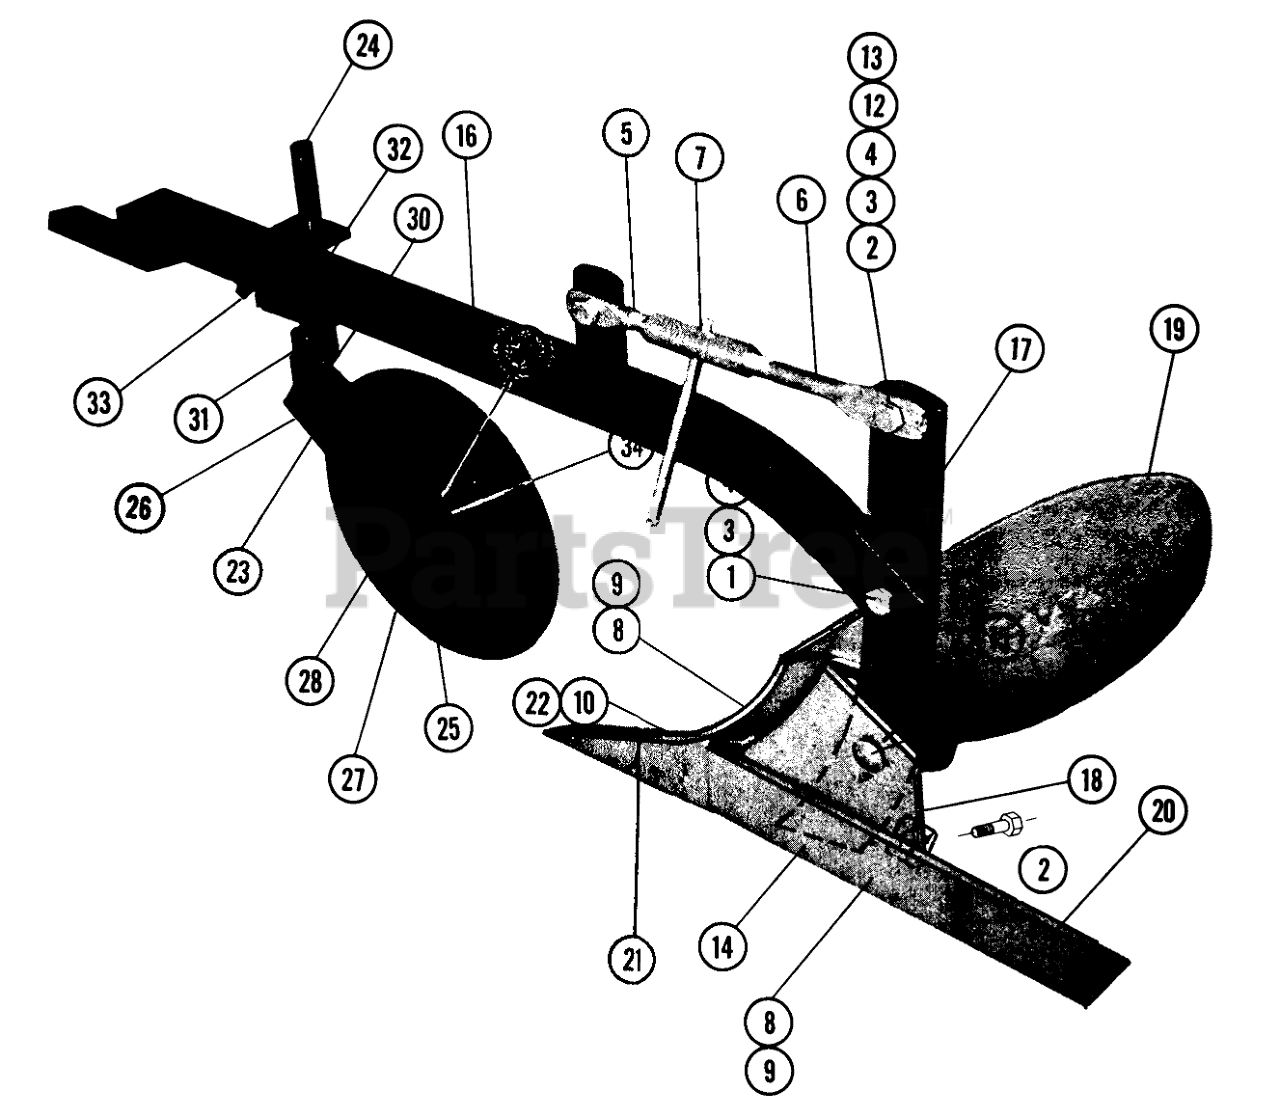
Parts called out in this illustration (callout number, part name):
1	Bolt-Hex 1/2-13 x 2
2	Bolt Hex 1/2-13 x 1 1/2
3	Lockwasher
4	Nut, 1/2-13
7	Coupling-Adjusting
8	Bolt-Plow 3/8-16 x 1
9	Nut-Sq. 3/8-16
10	Nut-Sq. 7/16-14
11	Nut-Square-1/2-13
12	5353 GILSON LGT WEI
13	Washer 9/16 SAE
14	Washer 9/16 SAE
15	Bolt-1/2-13 x 1-1/2 Carr.
16	Ass-y. Beam
17	Standard Assembly
18	Frog
19	Mold Board
20	Landslide Assembly
21	Point-8"
22	Bolt-Plow 7/16-14 x 1
